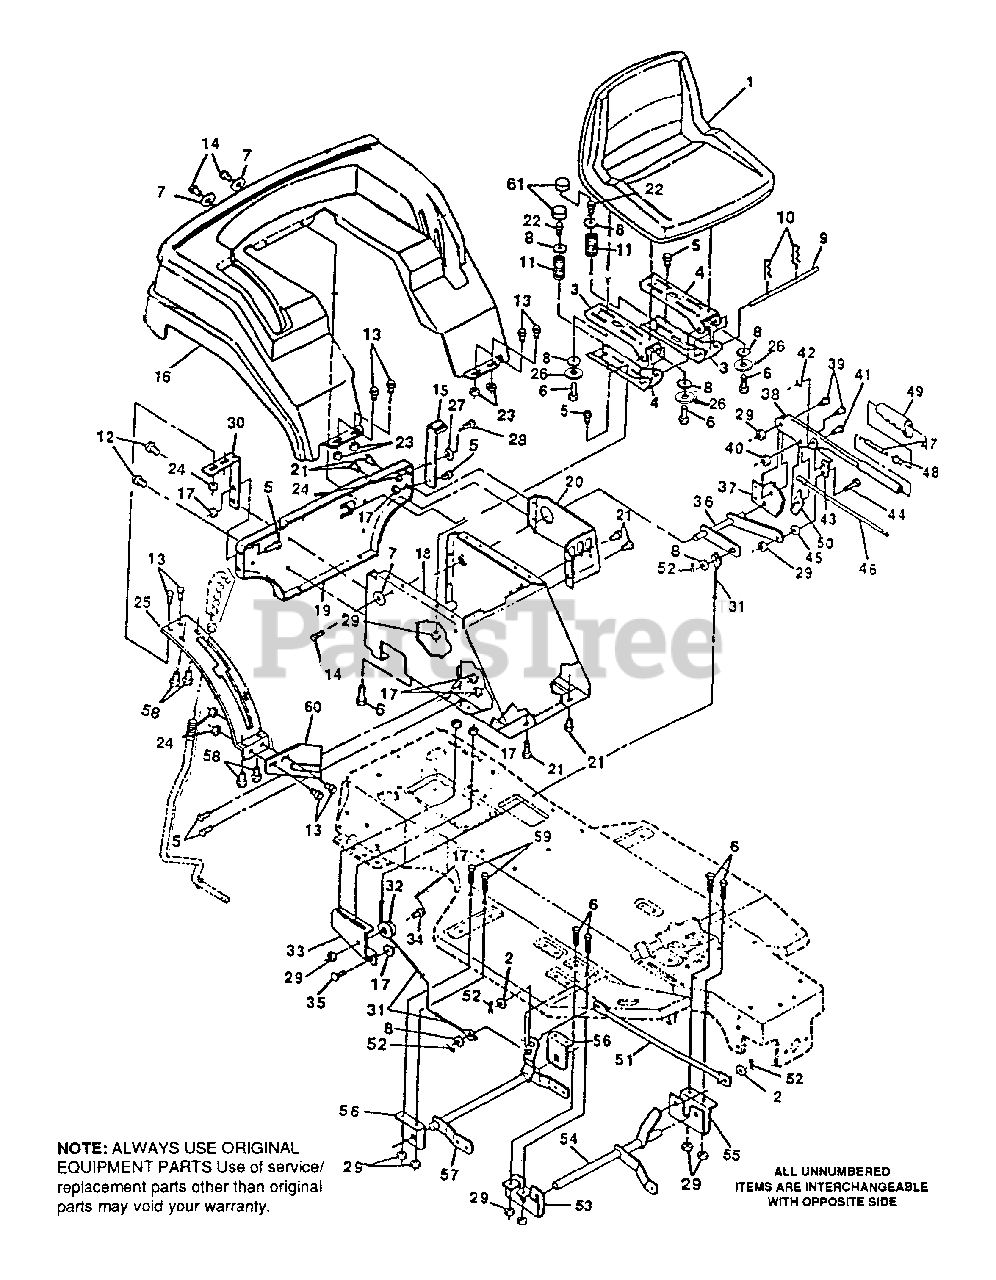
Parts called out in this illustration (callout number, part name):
2	Washer, Flat, 13/32 In.12
3	Channel, Seat
4	Channel, Seat
5	Screw, Hx Hd, Wd Fl 5/16-18 x 3/4 In.
6	Screw, Hx Hd, 5/16-18 x 3/4 In.
7	Washer, Flat, .281 x 1.00 x .063
8	Washer, Flat, 11/32 In.
9	Rod, Seat Support
10	Hair Pin, .073 Dia. x 1.13 In.
11	Seat Spring
12	Screw, Tap, 5/16-18 x 7/8 In.
13	Screw, Hx Hd, 1/4-20 x 5/8 In.
14	Screw, Hx, Wsher Hd, Tap 1/4-20 x 5/8 In.
15	Fender Support, L.H.
17	Nut, Hx, Wd Fl, Lk 5/16-18 Thd.
18	Seat Support
19	Support, Fender & Seat
20	Bracket, Support Engage
21	Screw, Hx Wshr Hd Tap, 5/16-18 x 1/2 In.
22	Screw, 5/16-18 x .63
23	Nut, Lock, 1/4-20 Thd.
24	Nut, Hx, Wd Fl Lk, 1/4-20 Thd.
26	Washer, Split.328x.60x.09
27	Washer, Flat
28	Screw, 1/4-20 x .75
29	Nut, Hx Ctrlk, 5/16-18 Thd.
30	Fender Support, R.H.
31	Cable, Deck Lift
33	Assembly, Pulley Bracket
34	Shoulder Bolt, 5/16-18 Thd.
35	Bolt, Carriage, 5/16-18 x 5/8 In.
36	Assembly, Upper Shaft
38	Lift Lever
39	Shoulder Bolt, 5/16-18 Thd.
40	Nut, Hx Wd Fl Lk 5/16-18 Thd.
41	Clevis Pin
44	Shoulder Bolt, 5/16-18 Thd.
46	Actuator Rod
47	Spring, Height Adjust
48	Knob, Height Adjust
49	Handle, Lift
50	Pawl, Height Adjust
52	Cotter Pin
53	Bracket, L.H. Front Hanger
54	Assembly, Front Lift Shaft
55	Bracket, R.H. Front Hanger
56	Bracket, Hanger
57	Assembly, Rear Lift Shaft
58	Screw, Hx Hd, Tap # 10 x 1/2 In.
59	Screw, Hx Hd, 5/16-18 x 5/8 In.
60	Support, Shift Plate
61	Cover, Seat Spring
